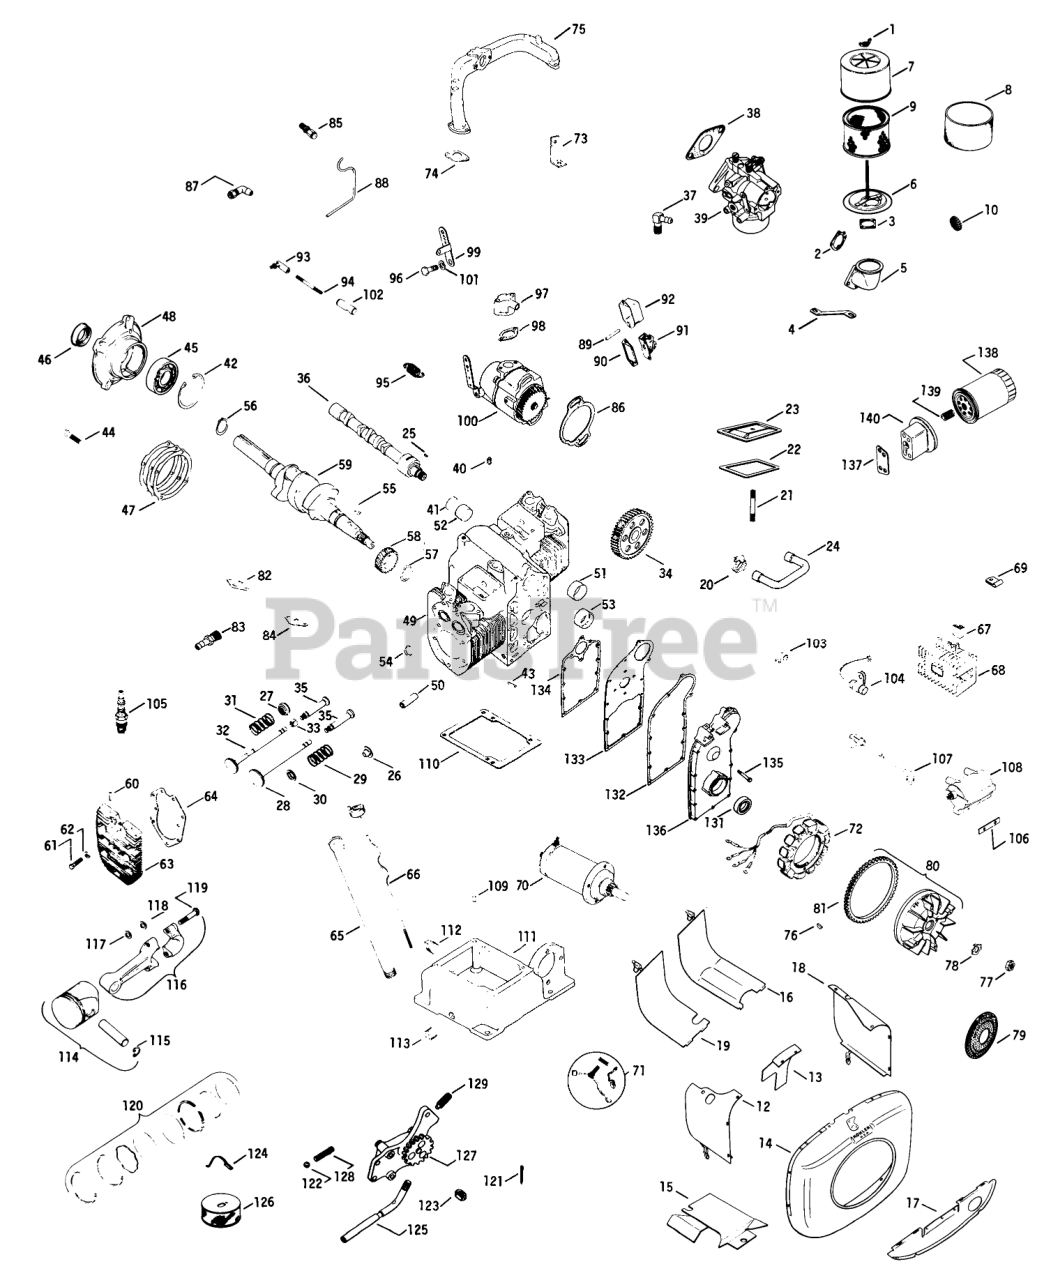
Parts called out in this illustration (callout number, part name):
1	Nut-Wing
2	Gasket
3	Gasket-Air Cleaner
4	Brace elbow
5	Elbow air cleaner
6	Base-Air Cleaner
7	Cover-Air Cleaner
8	Element
9	Element
10	Screen, elbow
12	Baffle #1 Cyl. Hd.
13	Baffle, #1 Upper Cyl.
14	Housing, Blower
15	Baffle
16	Baffle, #2 barrel
17	Baffle-Housing Support
18	Baffle, #2 cylinder head
19	Baffle, #1 barrel
20	Clamp-Hose
21	Stud, valve cover
22	Gasket-Valve Cover
23	Cover-Valve
24	Hose-Breather
25	Key-Woodruff
26	Retainer-Spring
27	Rotator, exhaust valve
28	Valve-Intake
29	Spring
30	Retainer-Spring
31	Spring, exhaust valve
32	Valve exhaust
33	Keeper, Valve
34	Gear, Camshaft
35	Tappet
36	Camshaft
37	Elbow
38	Gasket
39	Repairkit
39	Repair kit, choke (Not used prior to serial no. 6373502)
39	Carburetor-assembly (Replaced by 48 053 12)
40	Plug
41	Plug, Pipe
42	Plug-Welch
43	Pin
44	Screw-H.C.
45	Bearing-Ball
46	Seal-Rear Oil
47	Gasket-Closure Plate
48	Plate, rear closure
49	Crankcase-assembly
50	Guide Valve
51	Bushing
52	Bushing
53	Bearing
54	Insert
55	Key
56	Ring-Retaining
57	Ring, retaining 1-7/16 I.D.
58	Gear, crankshaft
59	Crankshaft
60	Pin, Roll 3/16x1-1/8
61	Screw
62	Washer
63	Head, Cylinder
64	Gasket, Cylinder Head
65	Tube, dipstick
66	Dipstick
67	Connector
68	Regulator
69	Clip
70	Starter Assembly
71	Kit, Brush
72	Stator
73	Lift Cable
74	Gasket
75	Manifold, Intake
76	Key-Woodruff
77	Nut-Hex.
78	Nut-Lock
79	Screen, grass
80	Flywheel-assembly
81	Gear, Ring
82	Gasket, pump
83	Connector
84	Cover, fuel pump
84	Connector
86	Gasket-Governor Housing
87	Elbow
88	Line, Oil
89	Rod, Breaker Push
90	Gasket, Cover
91	Breaker
92	Cover
93	Ball Joint
94	Rod-Throttle
95	Spring Governor
96	Screw Shoulder
97	Housing, breather (Includes valve)
98	Gasket
99	Lever-Throttle
100	Governor
101	Washer
102	Ball Joint
103	Clip-Cable
104	Condenser
105	Plug, spark
106	Plate Coil Mounting
107	Lead high tension
108	Coil
109	Pin-Dowel
110	Gasket-Oil Pan
111	Pan, oil-assembly
112	Plug
113	Plug, Pine
114	Piston-assembly (Std.)(Includes pin & retainers)
114	Piston-assembly (.003)(Includes pin & retainers)
114	Piston-assembly (.010)(Includes pin & retainers)
114	Piston-assembly (.020)(Includes pin & retainers)
114	Piston-assembly (.030)(Includes pin & retainers)
115	Retainer, pin
116	Rod, conn.-assembly (Std.)
116	Rod, Connecting (.010 U.S.)
117	Washer
118	Washer
119	Screw, connecting rod
120	Ring set (Std. & .003)(Svc)
120	Ring set (.010)(Service)
120	Ring set (.020)(Service)
120	Ring set (.030)(Service)
121	Pin-Cotter
122	Ball Steel
123	Palnut
124	Clip-Oil Tube
125	Tube-Oil Inlet
126	Strainer-Oil
127	Pump
128	Spring, Relief Valve
129	Screw
131	Seal rear oil
132	Gasket-Gear Cover
133	Plate-Gear Cover
134	Gasket-Gear Cover Plate
135	Screw-H.C.
136	Cover, gear
137	Gasket, adapter
138	Filter-Oil
139	Nipple
140	Adapter, filter
